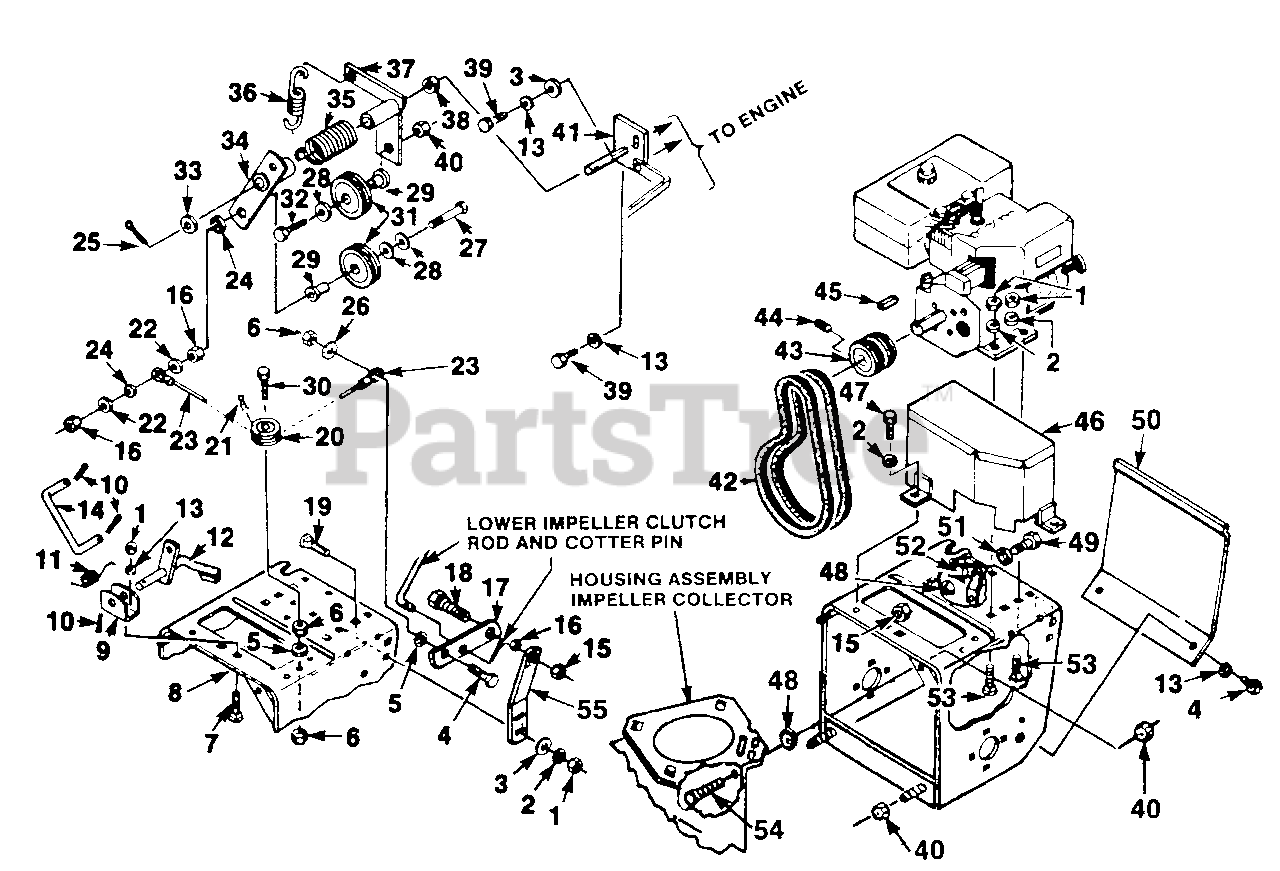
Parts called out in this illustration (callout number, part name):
1	NUT- Hex pivot mtg. 5/16-18
2	WASHER- Lock pivot mtg. 5/16"
3	WASHER- Flat pivot mtg. 5/16"
4	SCREW- Hex hd. 1/4-20 x 5/8"
5	WASHER- Lock hvy. 1/4"
6	NUT- Hex pulley mtg. 1/4-20
7	BOLT- Carriage 5/16-18 x 5/8"
8	FRAME ASSEMBLY
9	BRACKET- Brake rod support
10	PIN- Cotter 3/32 x 3/4"
11	SPRING- Brake rod torsion
12	BRAKE ARM ASSEMBLY
13	WASHER- Lock med. 5/16"
14	LINK- Brake
15	NUT- Hex C/lock 5/16-18
16	NUT- Hex jam 3/8-16
17	BELL CRANK ASSEMBLY
18	BOLT- Shoulder washer face 5/16-18
19	BOLT- Pivot mtg. carr. 5/16-18 x 3/4"
20	PULLEY- Control cable
21	PIN- Cotter 1/16 x 2"
22	WASHER- Flat
23	CABLE- Impeller clutch
24	WASHER- Lock med. 3/8"
25	PIN- Cotter ext. prong 1/8 x 1"
26	WASHER- Flat 1/4"
27	SCREW- Hex hd. 3/8-16 x 2"
28	WASHER- Flat SAE 3/8"
30	SCREW- Hex hd. 1/4-20 x 1/2"
31	PULLEY- Idler
32	SCREW- Hex hd. 3/8-16 x 1 1/2"
33	WASHER- Flat idler cam retaining 17/32"
34	IDLER ARM ASSEMBLY
35	SPRING- Brake
36	SPRING- Traction Idler
37	TRACTION IDLER ARM
38	SPACER- Idler
39	SCREW- Hex hd. cap 5/16-24 x 3/4"
40	NUT- Hex lock 3/8-16
41	IDLER PLATE ASSEMBLY
42	BELT- Drive
43	PULLEY- Engine
44	SCREW- Set soc. hd. 5/16-18 x 1/2"
45	KEY- Engine pulley mtg.
46	BELT- Guard
47	SCREW- Hex type T 5/16-18 x 5/8"
48	WASHER- Flat shift lever mtg. 5/16"
49	BOLT- Shift lever mtg.
50	COVER- Back
51	WASHER- Spring shift lever mtg.
52	LEVER- Shift
53	BOLT- Shnk. carr. (824) 5/16-18 x 1 1/2"
54	BOLT- N reg. carr. 3/8-16
55	BRACKET- Belt crank pivot
